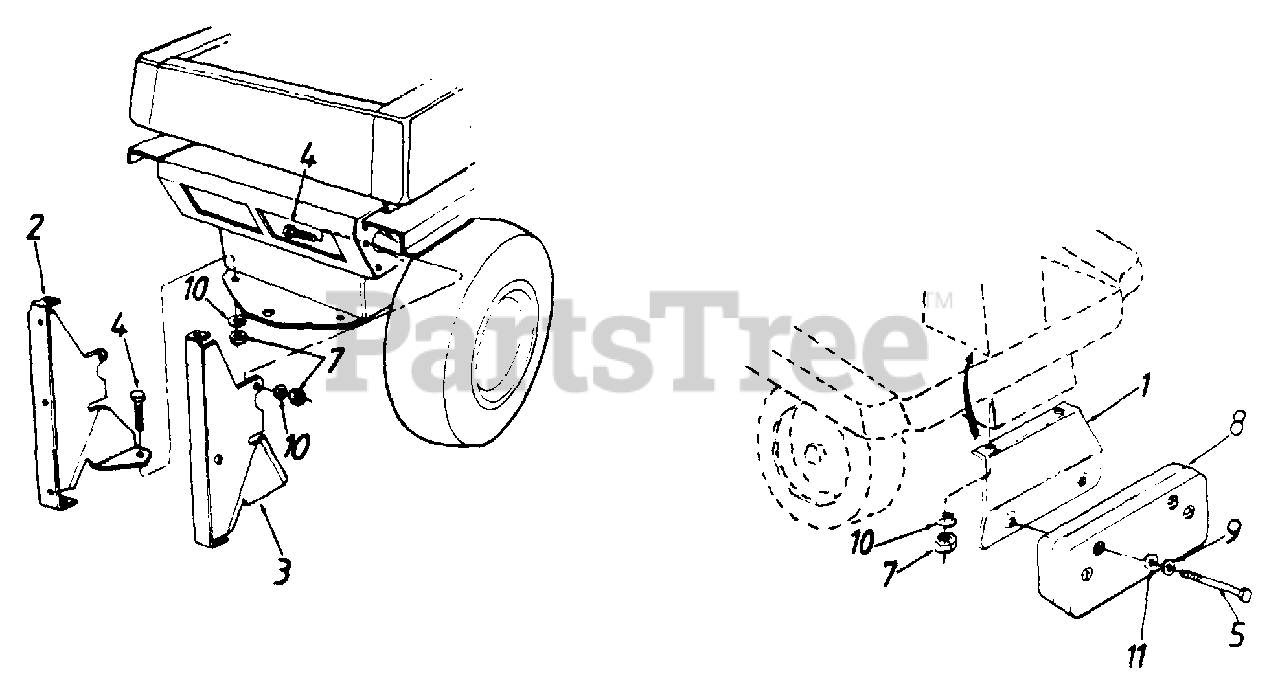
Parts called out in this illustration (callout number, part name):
1	Counterweight Support Brkt.
2	Catcher Support Brkt. - R.H.
3	Catcher Support Brkt. - L.H.
4	Hex Bolt 5/16-18 x 1.0" Lg.
5	Hex Bolt 3/8-16 x 4.5" Lg.
7	Hex Nut 5/16-18 Thd.
8	Front Counterweight
9	Bell-Wash. 3/8" I.D.
10	L-Wash. 5/16" I.D.
11	Fl-Wash. .390" I.D. x 1.12" O.D.
